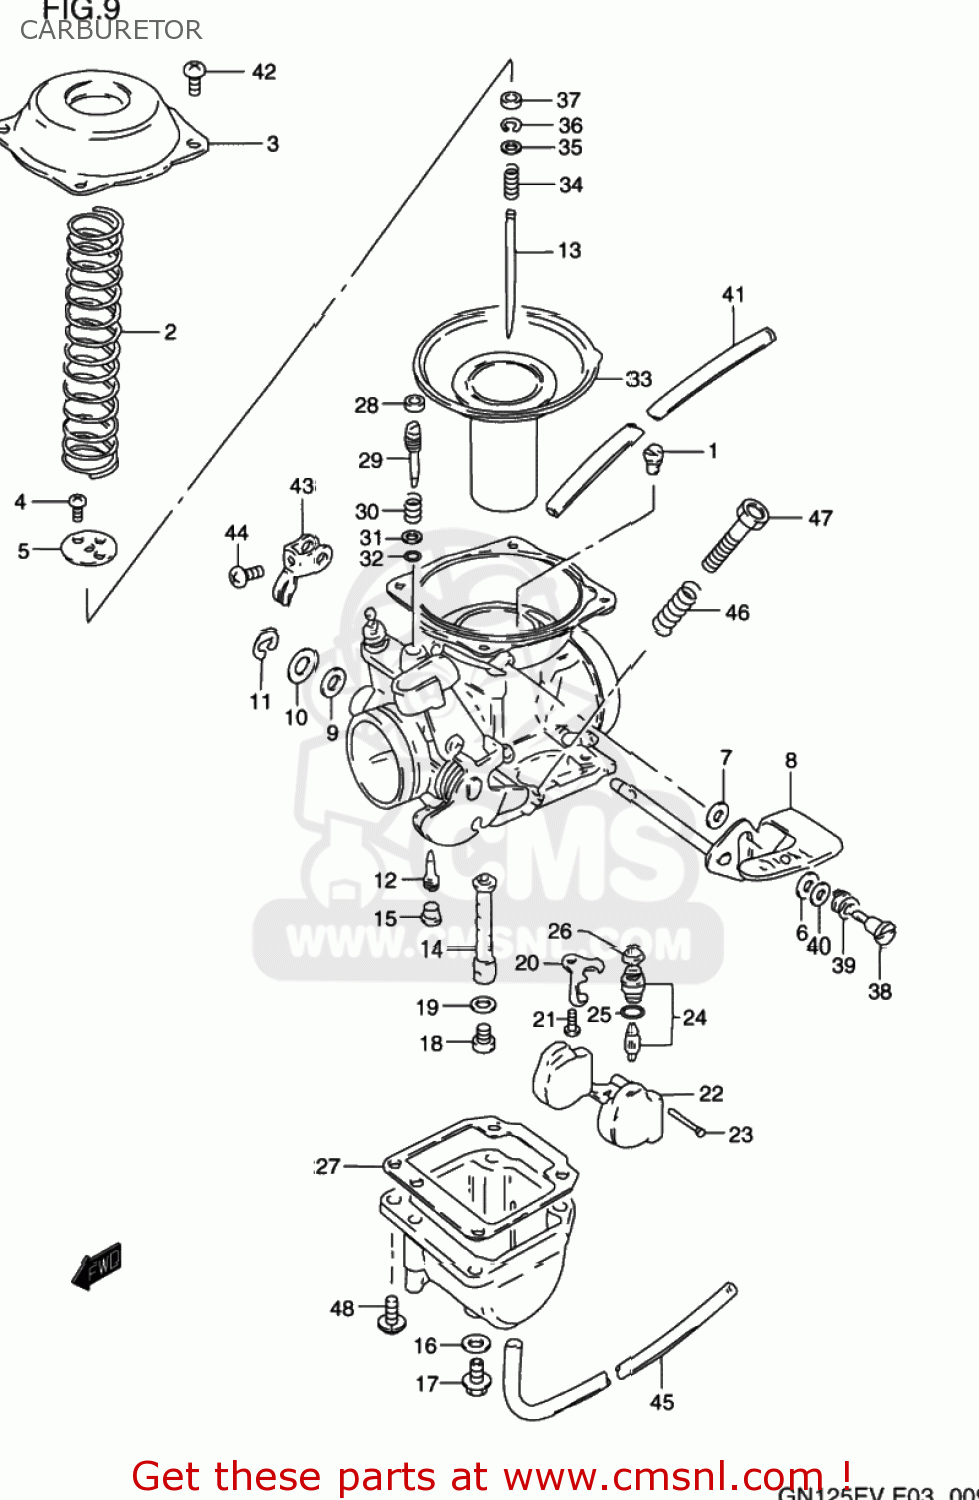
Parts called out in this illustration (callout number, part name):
1	JET,MAIN(180)
2	SPRING
3	COVER
4	SCREW
5	PLATE
6	PACKING (NAS)
7	WASHER(4.1X12X0.8)
8	SHAFT ASSY,STARTER
9	SEAL
10	GASKET,THROTTLE SHAFT (NAS)
11	E RING
12	JET,PILOT(35)
13	NEEDLE,JET
14	JET,NEEDLE(P-2)
15	PLUG,NEEDLE JET
16	GASKET (NAS)
17	PLUG,DRAIN
18	JET,MAIN(97.5)
19	WASHER,NEEDLE NOZZLE
20	PLATE
21	SCREW 4X6
22	FLOAT
23	PIN,FLOAT
24	VALVE ASSY,NEEDLE
25	O-RING,NEEDLE VALVE
26	FILTER
27	GASKET,FLOAT CHAMBER (NAS)
28	PLUG
29	SCREW,PILOT
30	SPRING
31	WASHER
32	O RING,PILOT AIR SCREW
33	DIAPHRAGM ASSY
34	SPRING
35	WASHER
36	CLIP
37	RING
38	SCREW
39	SPRING
40	WASHER,STARTER SHAFT
41	HOSE(5X8.2X600)
42	SCREW
43	LEVER
44	SCREW
45	HOSE(3.5X6.5X600)
46	SPRING,THROTTLE SCREW
47	SCREW,THROTTLE STOP
48	SCREW
